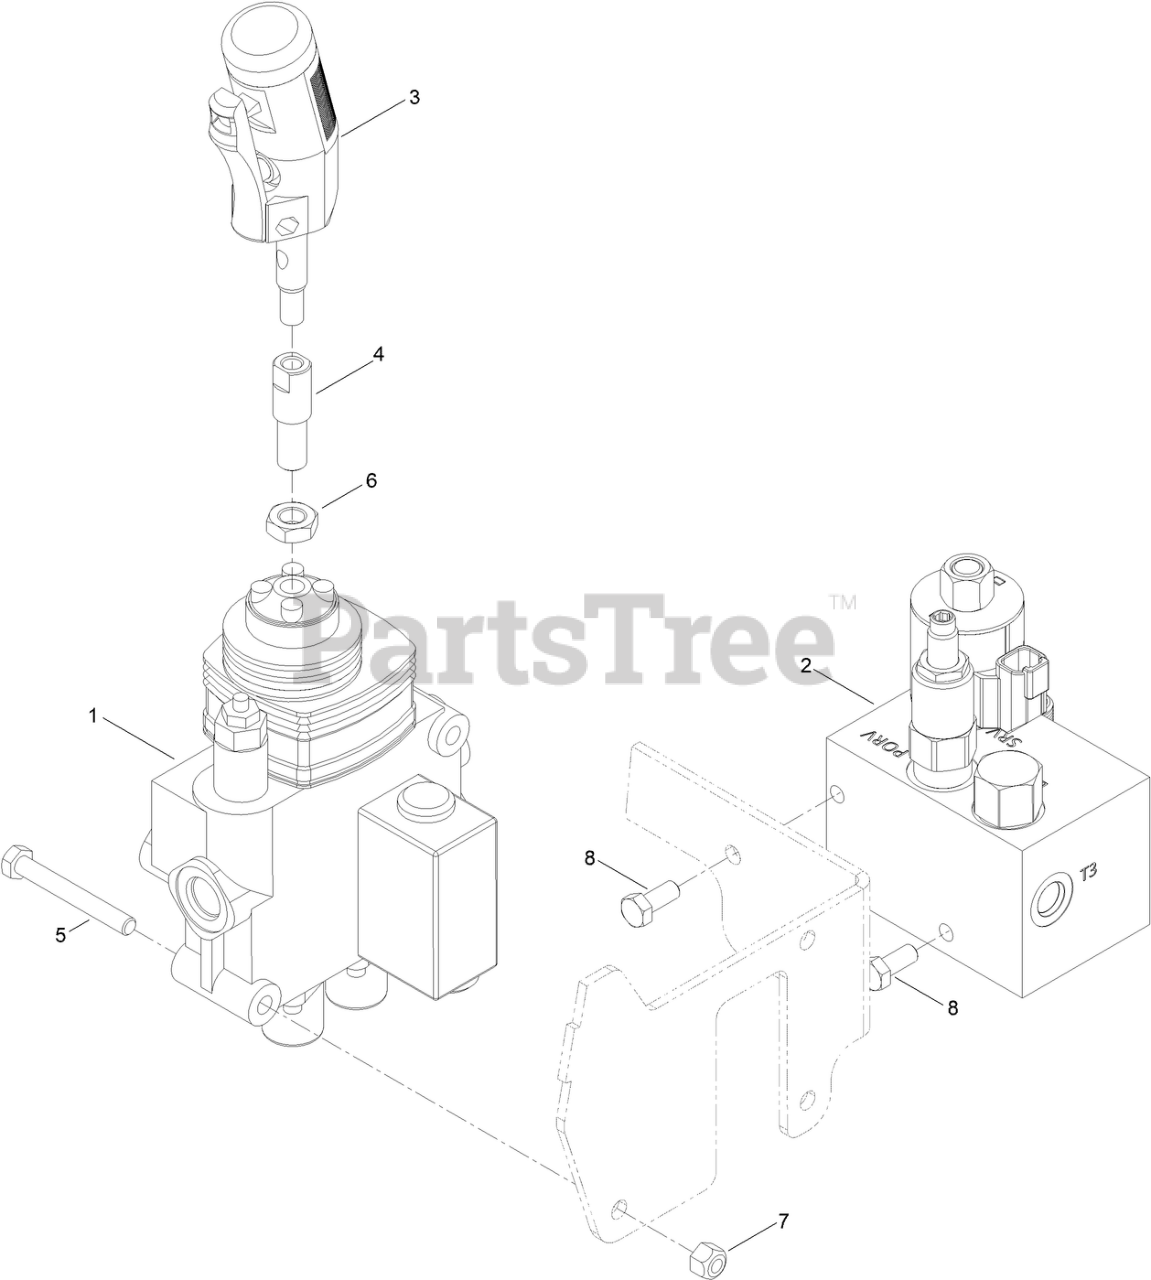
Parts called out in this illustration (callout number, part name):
1	HYD VALVE ASM
2	CUTTER WHEEL VALVE ASM
3	TWO BUTTON HANDLE GRIP ASM
4	ADAPTER-HANDLE
5	SCREW-HH
7	NUT-LOCK, NI
8	SCREW-HH
